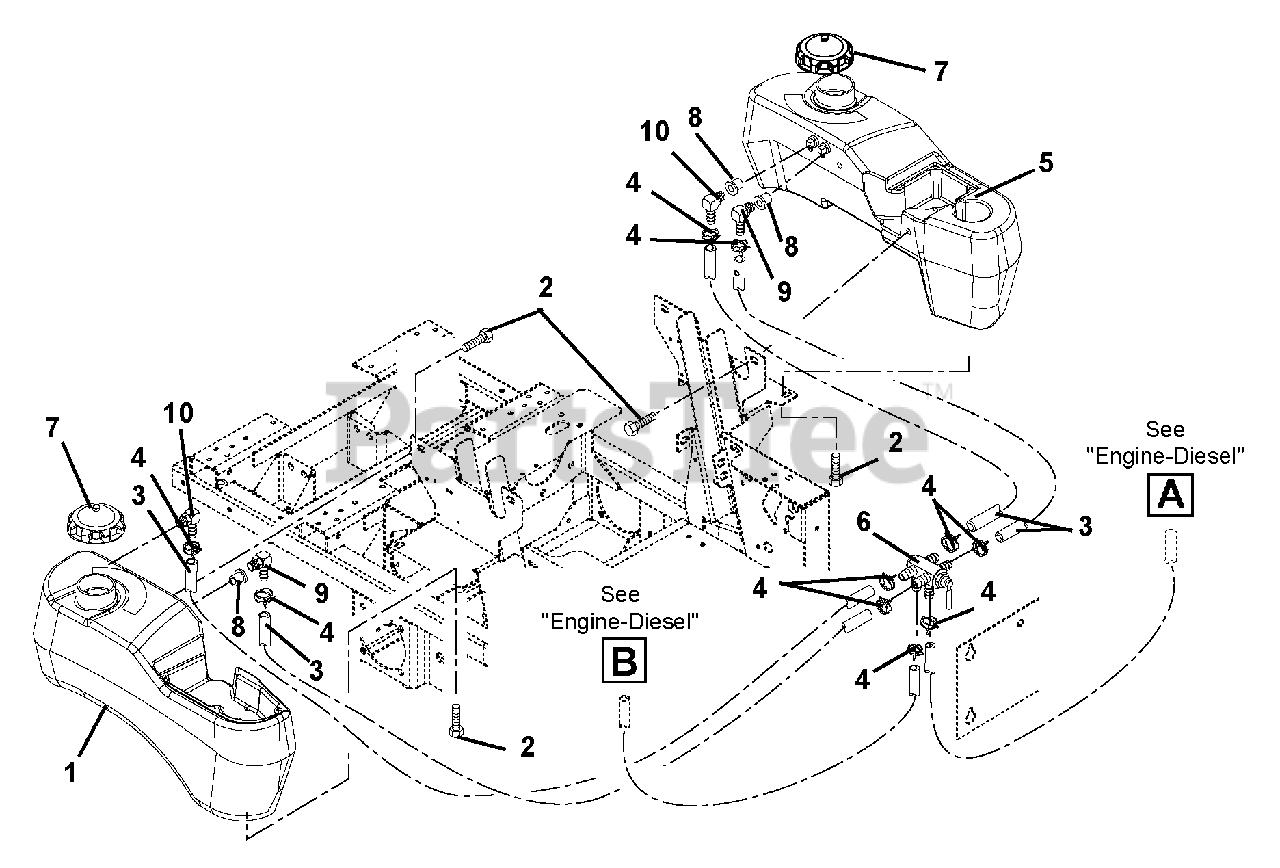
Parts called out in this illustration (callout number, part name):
1	Tank, Fuel-Right Hand
2	Bolt, SEMS .31-18 x .62
3	Hose, .31 ID
4	Clamp, Hose Wire .52/.55
5	Tank, Left Hand Fuel (EYE-Q) 200 Series-EFI
6	Valve, Fuel
7	Cap, Fuel
8	Grommet, Black
8	Grommet, Orange
9	Fitting, Tank
10	Fitting, Tank
